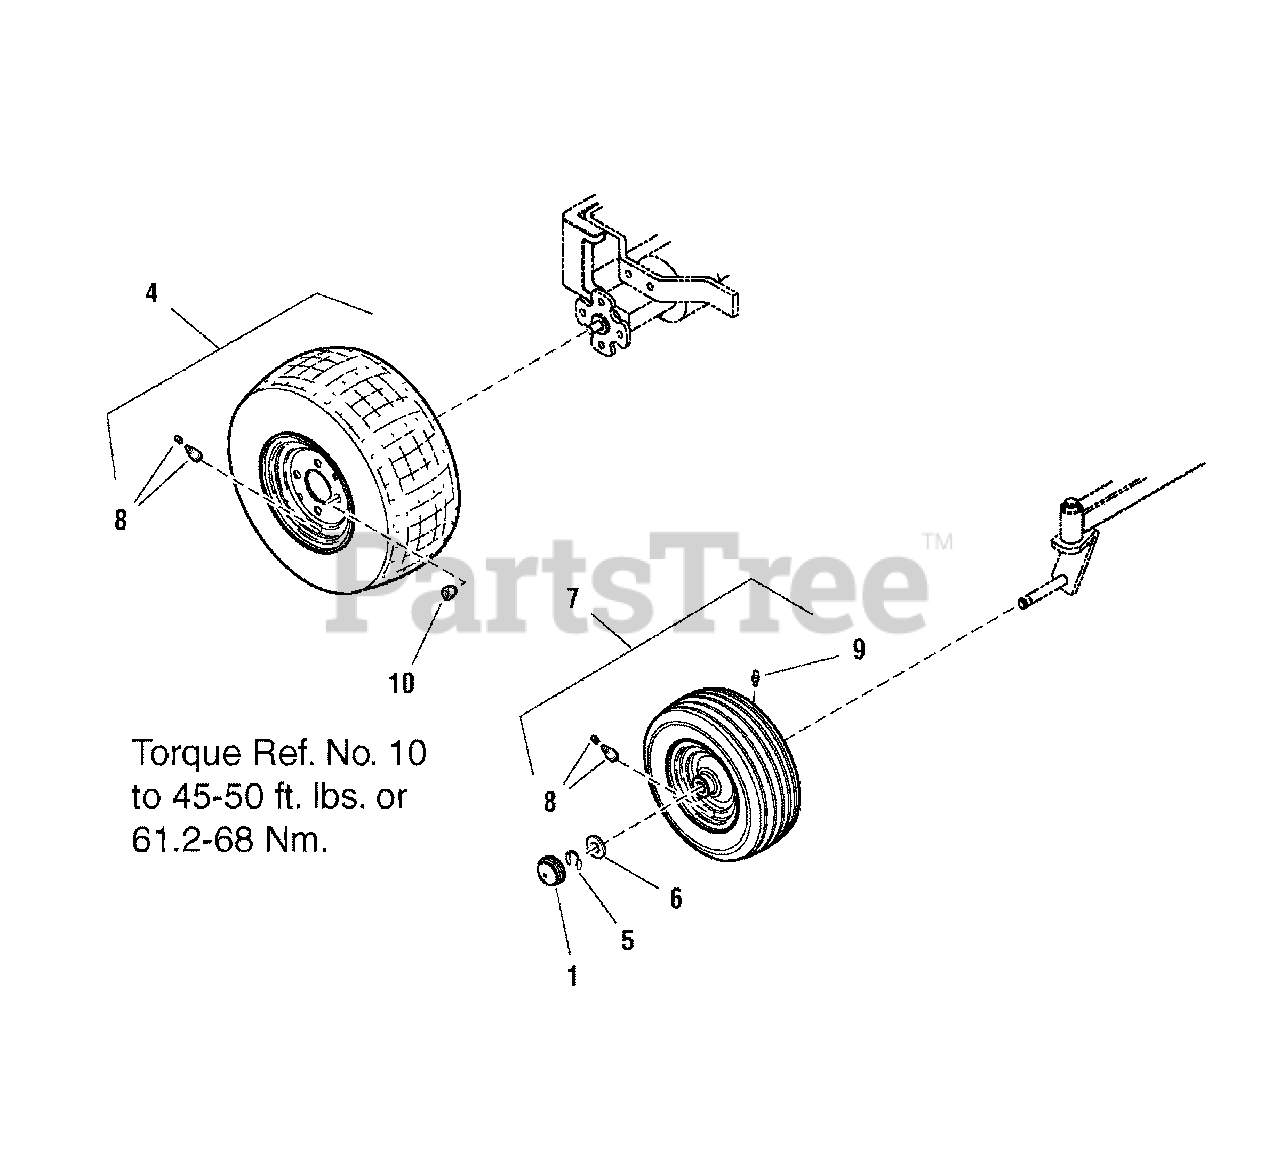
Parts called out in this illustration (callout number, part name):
1	CAP, Hub, 1-1/2 ID Gray Poly 1.3 HI
4	WHEEL & TIRE ASSEMBLY, Rear
5	RING, Klipring for 3/4 DIA Shaft
6	WASHER, 3/4, 0.76 ID x 1.62 OD x .12 THK
7	WHEEL & TIRE ASSEMBLY, Front
8	VALVE STEM & CAP
9	FITTING, Lube
10	NUT, Hex Lug, 7/16-20
